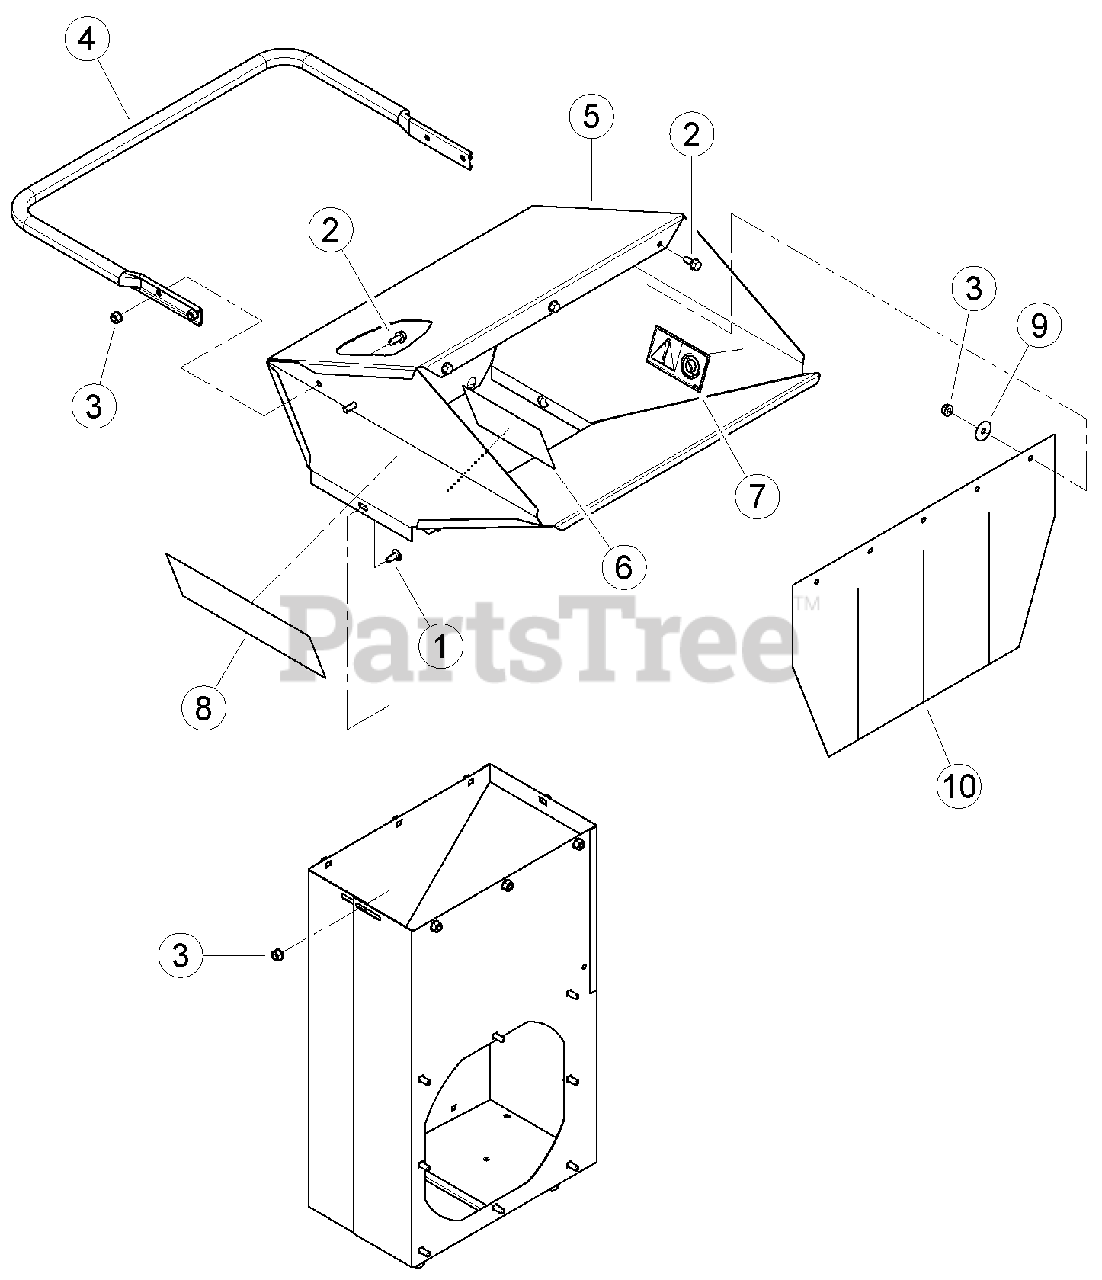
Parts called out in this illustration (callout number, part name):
1	BOLT, 5/16-18 X 3/4 CRG SN GR5
2	BOLT, 5/16 X 3/4 FLANGE NC
3	NUT, 5/16-18 NYLOCK-FLANGE
4	HANDLE, RENTAL HOPPER
5	ASSEMBLY, WIDE BODY RENTAL HOPPER
6	DECAL, BLADE DANGER ISO
7	DECAL, SHREDDER SIZE ISO
8	DECAL, ECHO BEARCAT 12.00 X 4.00
9	WASHER, 5/16 FENDER ZP
10	BELTING, RENTAL HOPPER
